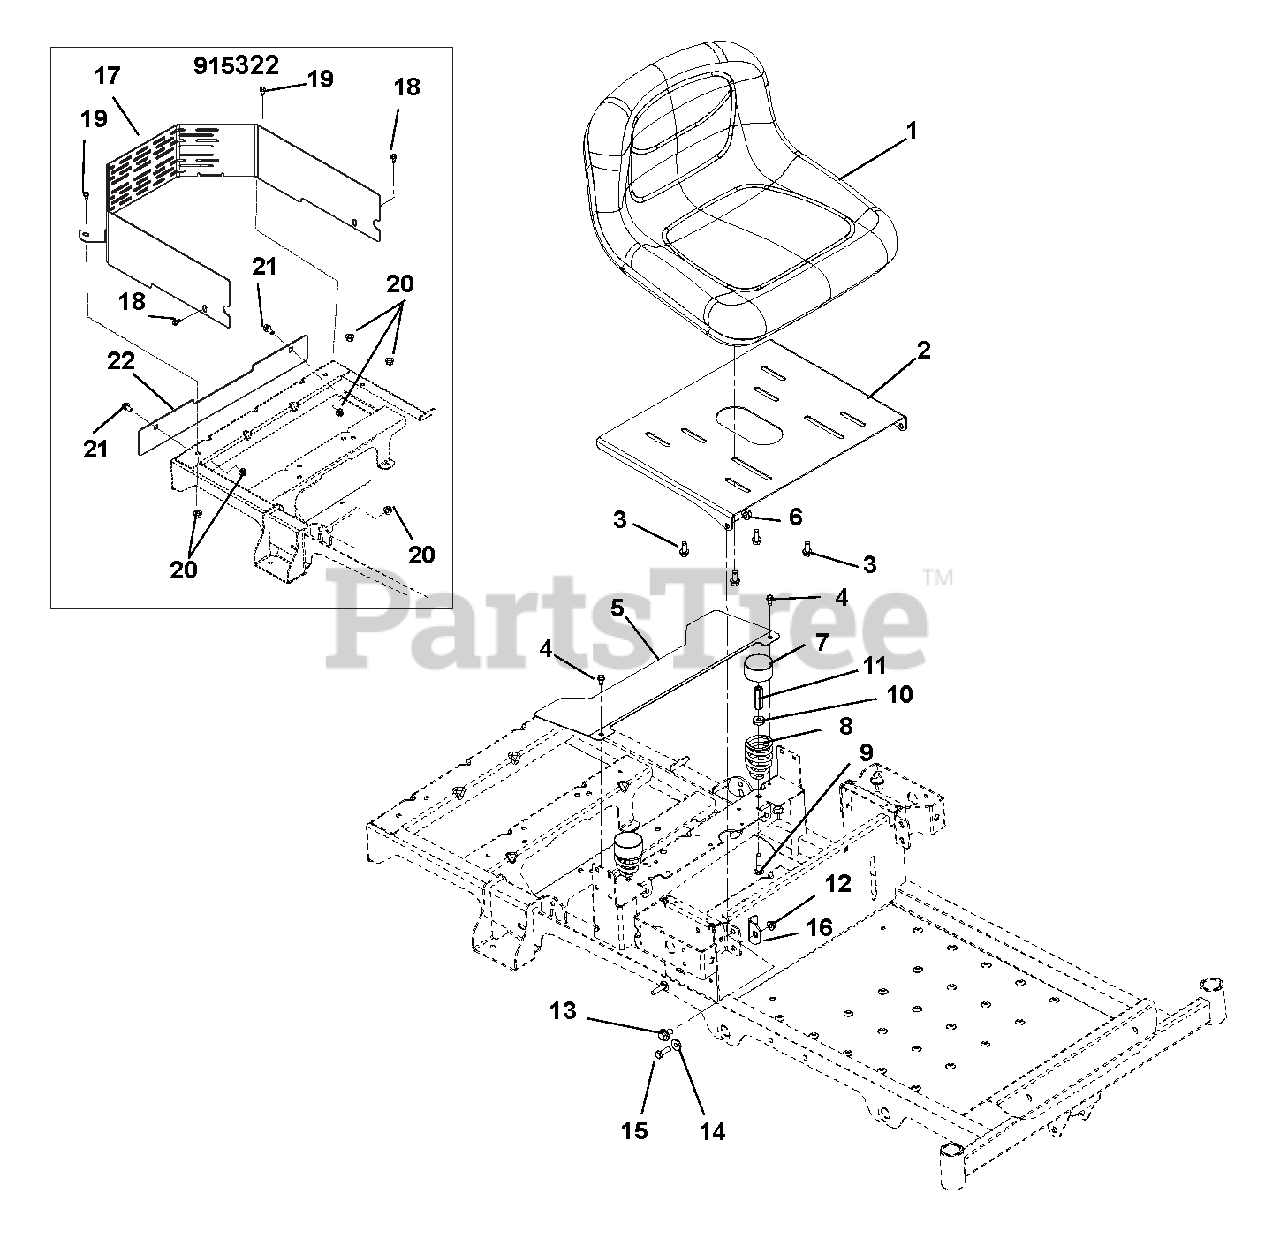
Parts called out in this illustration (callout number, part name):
1	SEAT-13" GREY
2	PLATE, SEAT
3	5/16-18X3/4 HX/W/HD WHIZ
4	@SCR-TAP .25-20X.50 HWH TR YWZ
5	GUARD, FAN
5	COVER, ZOOM CE FAN
6	@NUT-LK-TOP-FLG .38-16 YWZC
7	HUB CAP
8	SPRING, SEAT
9	@BLT-RDHDSQNK .31-18X1.50 G5YZ
10	WSHR-FL-STL .328X.87X.179 YWZC
11	NUT, COUPLING 5/16-18 X 1 3/4
12	@NUT-LK-NYL-FLG .31-18 YWZC
13	BOLT-SHLDR .375-16X.150
14	BSHG, FLG .325X.499X.26X.88
15	@BLT-HEX .31-18X1.00 GR5 YWZC
16	BRKT, SEAT STOP
17	WALL, CE REACH-IN (ZOOM)
18	@BLT-HEX .38-16X.75 GR5 YWZC
19	@BLT-HEX .38-16X1.00 GR5 YWZC
20	NUT-LK-CTR-FLG .38-16 YWZC
21	@BLT-RDHDSQNK .38-16X.75 G5YZ
22	FLANGE, ZOOM MUFFLER (CE)
